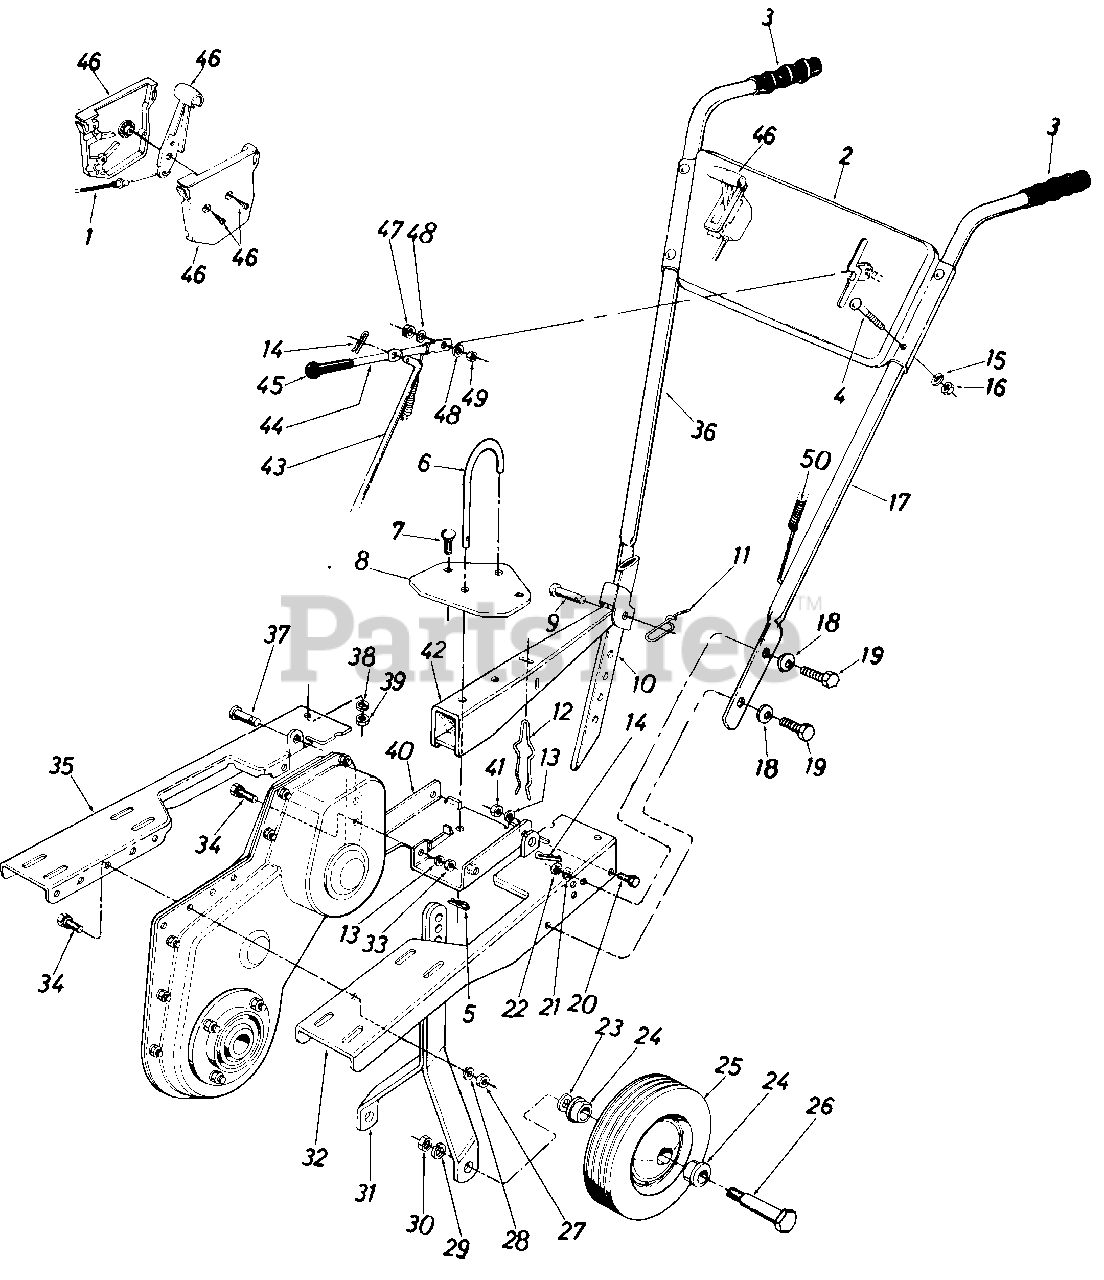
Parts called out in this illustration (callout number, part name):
1	Throttle Control Wire-35
2	Handle Panel Ass'y.
3	Handle Grip
4	Carriage Bolt 5/16-18 x 1.75 Lg.*
5	Internal Cotter Pin
6	"U"-Clevis Pin .500 Dia.
7	Carriage Bolt 5116-18 x .75 Lg.*
8	"U"-Channel Plate
9	Clevis Pin .500 Dia.
10	Depth Bar
11	Spring Pin
12	Depth Bar Spri ng
13	L-Wash. 5/16" I.D.
14	Internal Cotter Pin
15	L-Wash. 5/16" I.D.
16	Hex Nut 5/16-18 Thd.*
17	Handle-L.H.
18	Belleville Wash. 3/8 I.D.
19	Hex Bolt 3/8-16 x 1.00 Lg.
20	Hex Bolt 5/16-18 x .75 Lg.
21	L-Wash. 3/8 I.D.
22	Hex Nut 3/8-16 Thd.
23	Belleville Wash. .505 I.D. x 1.00" O.D.
24	Fl. Bearing w/Flats .631 I.D.
25	Wheel Ass'y. Comp. 10 x 1.75
26	Shoulder Bolt .625 Dia. x 2.75 Lg.
27	Hex Nut 5/16-18 Thd.
28	L-Wash. 5/16" I.D.
29	L-Wash. 1/2" I.D.
30	Hex Ins. L-Nut 1/2-0 Thd.
31	Wheel Bracket Ass'y.
32	Engine"U"-Channel Ass'y.-L.H.
33	Hex Nut 5/16-18 Thd.
34	Hex Sems Bolt 5/16-18 x 1.00" Lg.
35	Engine"U"-Channel Ass'y.-R.H .
36	Hand le-R.H .
37	Clevis Pin
38	L-Wash. 5116" I.D.
39	Hex Nut 5/16-18 Thd.
40	"U"-Channel Bracket Ass'y.
41	Hex Nut 5/16-18 Thd.
42	Tailpiece Ass'y.
43	Control Rod
44	Clutch Lever
46	Throttle Control Box Ass'y.
47	Rubber Wash.
48	Fl-Wash. .344" I.D. x .880 O.D. x .06
49	Hex Cent. L-Nut 5/16-18 Thd.
50	Extension Spring .75" O.D. x 11.0" Lg.
